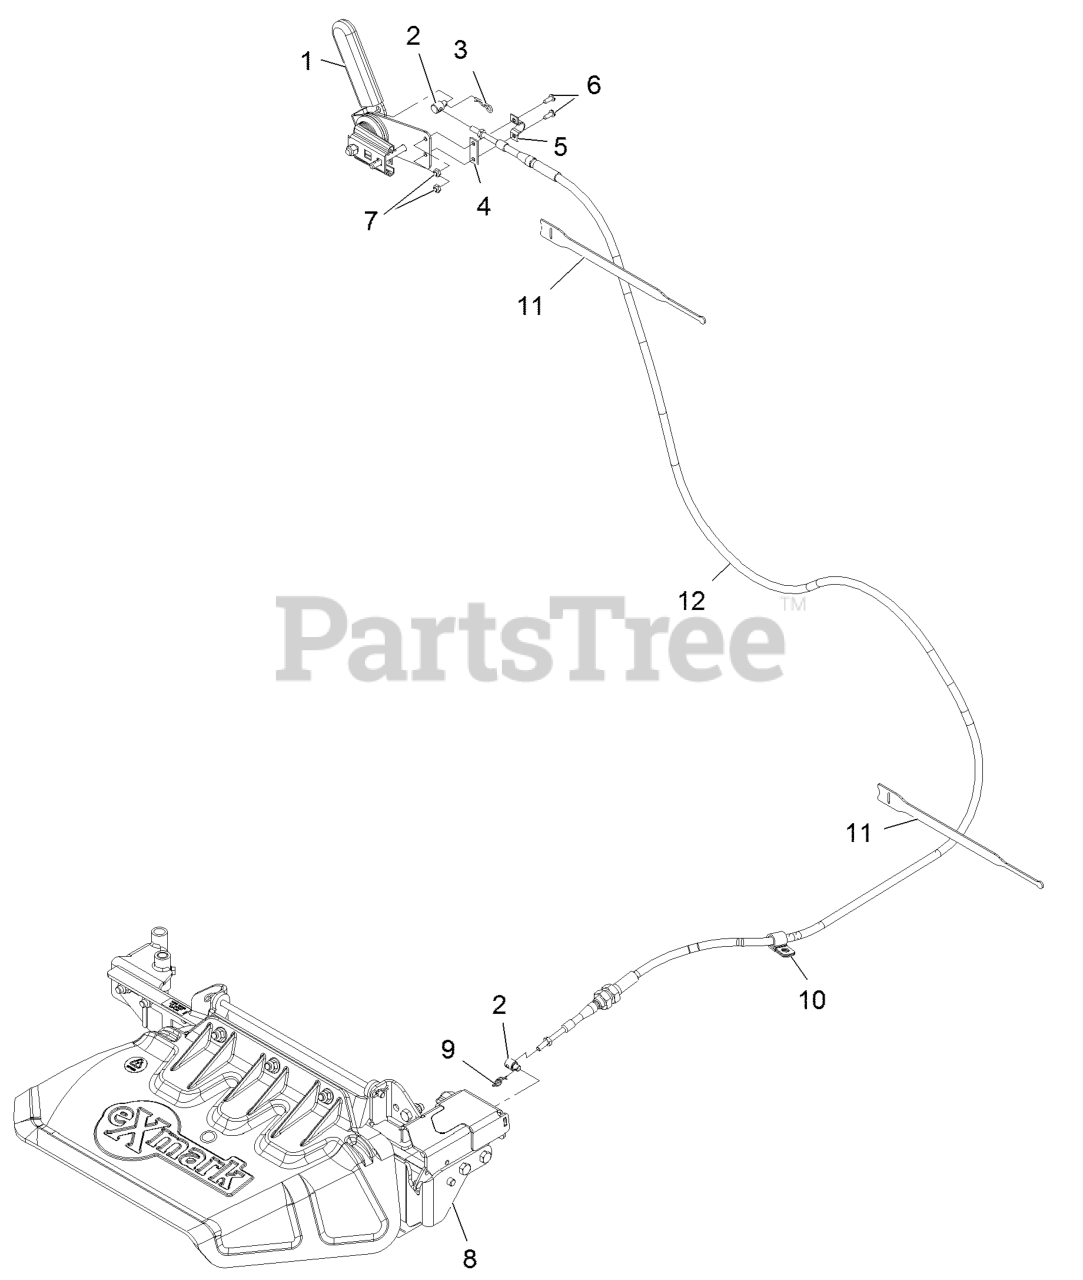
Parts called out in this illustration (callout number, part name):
1	ASM, HAND LEVER
2	PIVOT, CONTROL CABLE
3	PIN-COTTER
4	SHIM,CONTROL CABLE
6	SCREW-PPH
7	NUT-LOCK, NI
8	ASM, OCD
9	PIN-COTTER, LOCKING
10	CLIP-LOOM
11	STRAP-VELCRO, CABLE TIE
12	CABLE-DISCHARGE GATE
